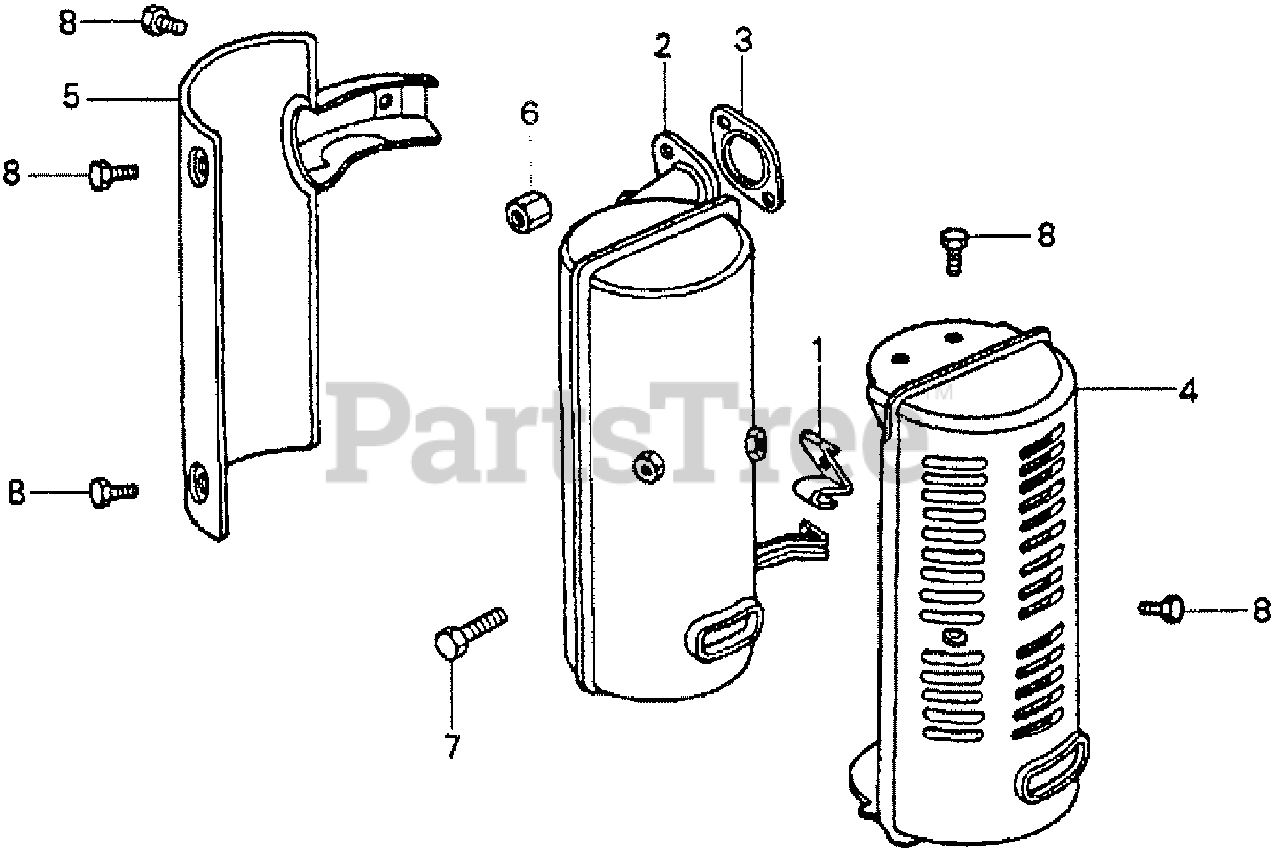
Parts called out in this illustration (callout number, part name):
1	HOLDER, THROTTLE CABLE
2	MUFFLER (NOT AVAILABLE)
3	GASKET, MUFFLER (NOT AVAILABLE)
4	PROTECTOR, MUFFLER
5	SEPARATOR, MUFFLER
6	NUT, HEX. (6MM)
7	BOLT, HEX. (8X18)
8	BOLT, HEX. (6X6)
